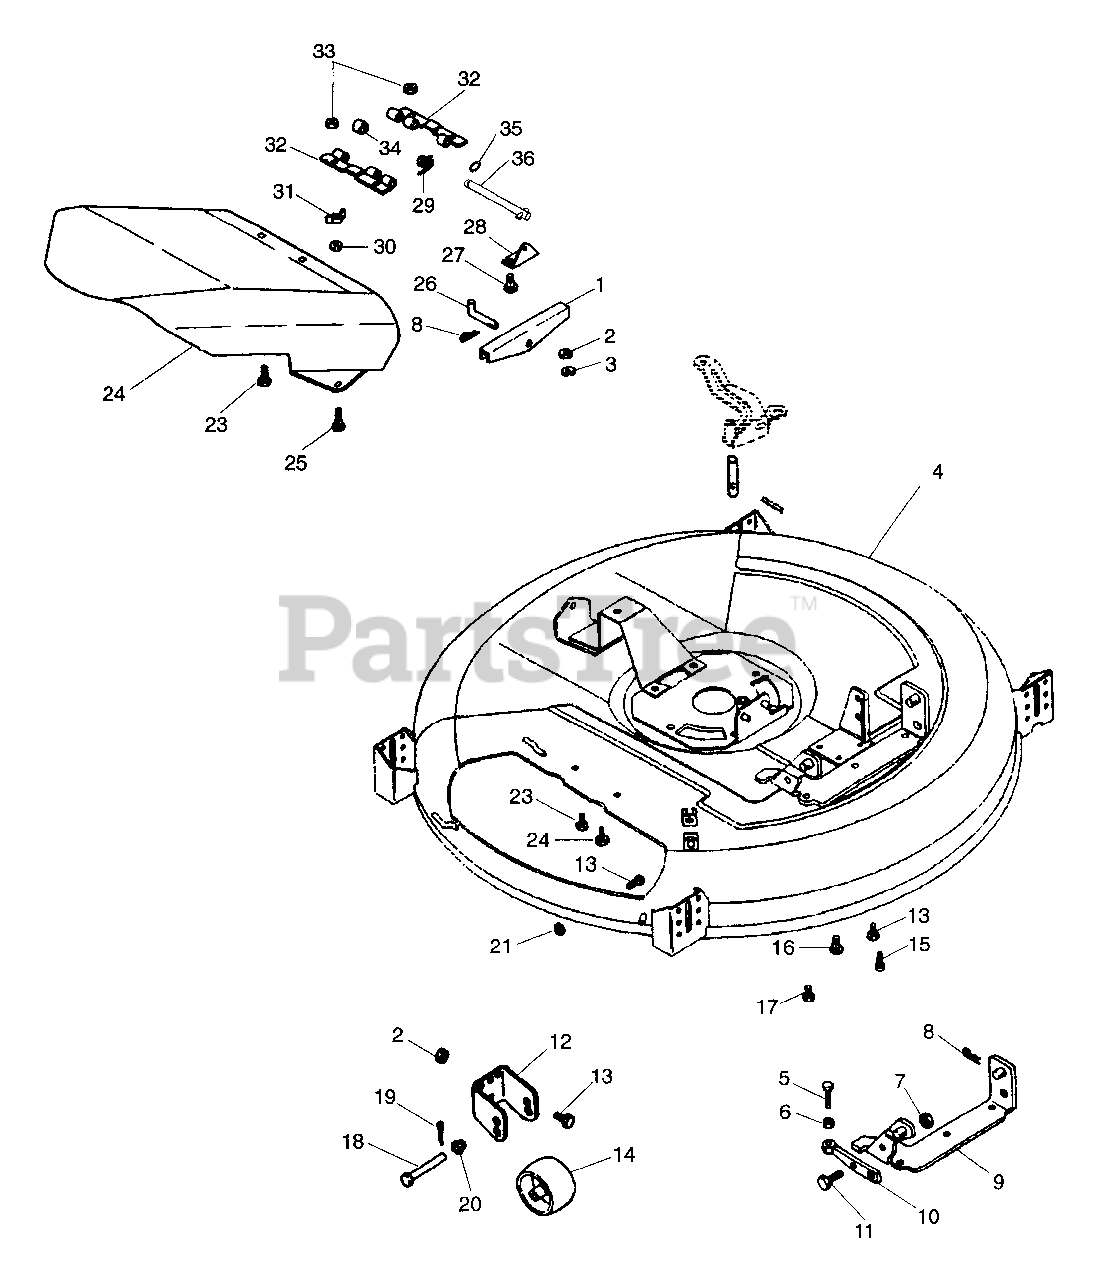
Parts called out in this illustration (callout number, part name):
1	SWIVEL BRACKET
2	NUT-FLG. .312-18 PL
3	WSHR-LK .312X.097 PL HVY
4	28"MOWER PAN W/DEFLECTOR&DECAL
4	28" MOWER PAN SERVICE ASSEMBLY
4	30"MOWER PAN W/DEFLECTOR&DECAL
4	30" MOWER PAN ASSEMBLY
4	32"MOWER PAN W/DEFLECTOR&DECAL
4	32" MOWER PAN ASSY RETROFIT
5	BLT-HEX .38-16X1.25 PL GR5
6	NUT-JAM .375-16 PL
7	NUT-LK-CTR .375-16 GR A PL
8	PIN-HAIR INT .08X.38X1.42 YWZC
9	FRONT BRACKET 30"
10	ADJUSTING ARM
11	@BLT-HEX .38-16X.88 PL GR2
12	ROLLER CLEVIS
13	BLT-RDHDSQNK .312-18X.62SHTPL
14	ROLLER
15	BLT-RDHDSQNK .25-20X.75
16	SCR-TAP .375-16X .50 HWH PL TR
17	BLT-RDHDSQNK .31-18X1.00 PL
18	PIN-CLEV .371X3.25 YWZC
19	PIN-COTR .15 X 1.0 PL
20	BSHG-FLG .372X.500X.312X.625NY
21	NUT-PUSH .312
22	BLT-RDHDSQNK .31-18X.75 GR5 PL
23	BLT-RDHDSQNK .25-20X.62 PL
24	PAN CHUTE EXTENSION
24	28" DEFLECTOR W/DECALS
24	32" DEFLECTOR W/DECAL
25	BLT-RDHDSQNK .25-20X1.00 GR5
26	CLEVIS PIN
27	SCR-TAP .312-18X.50 HWH PL TR
28	REAR MOUNTING BRACKET
29	SG-TORS .095X.50X 1.0
29	SG-TORS .090X.37X.63
30	WSHR-FL-STL .328X.875X.062 PL
31	NUT-WING W/INSERT .312 - 18
32	HINGE PLATE
33	NUT-LK-CTR .250-20 PL
34	BSHG-SLV .334 X .502 X 1.437
35	RG-RTNG-EXT .312X.025
